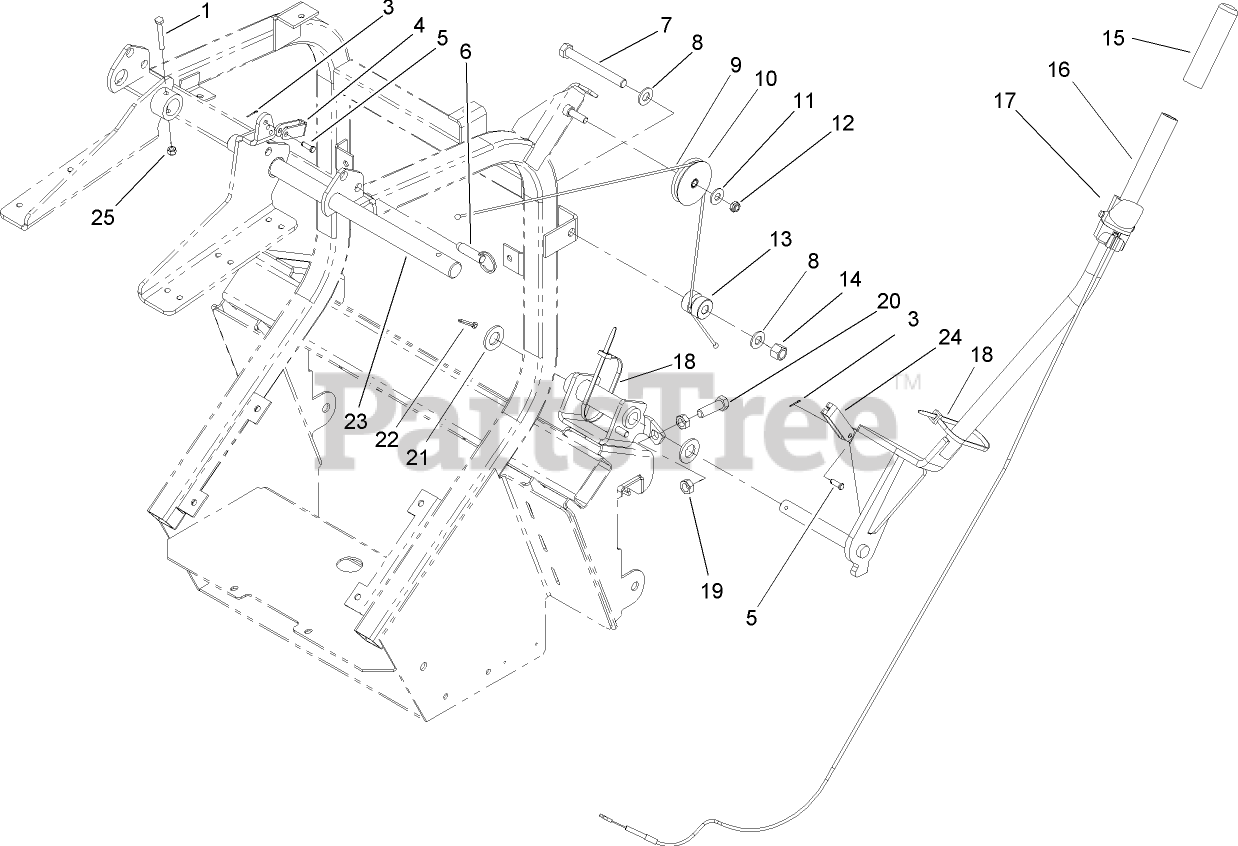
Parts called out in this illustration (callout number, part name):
1	SCREW-HH
3	PIN-COTTER
4	CLEVIS-SHORT
5	PIN-CLEVIS
6	PIN-RELEASE, QUICK
7	SCREW-HH
8	WASHER-FLAT
9	CABLE-DOOR
10	PULLEY ASM
11	WASHER-FLAT
12	NUT-LOCK, NI
13	ROLLER-CABLE
14	NUT-LOCK, NI
15	GRIP-FOAM
16	DUMP ARM ASM
17	LATCH-CABLE, DUMP
18	TIE-CABLE
19	NUT-JAM
20	SCREW-HH
21	WASHER-FLAT
22	PIN-COTTER
23	SHAFT-HINGE
24	CLEVIS-LONG
25	NUT-LOCK, NI
